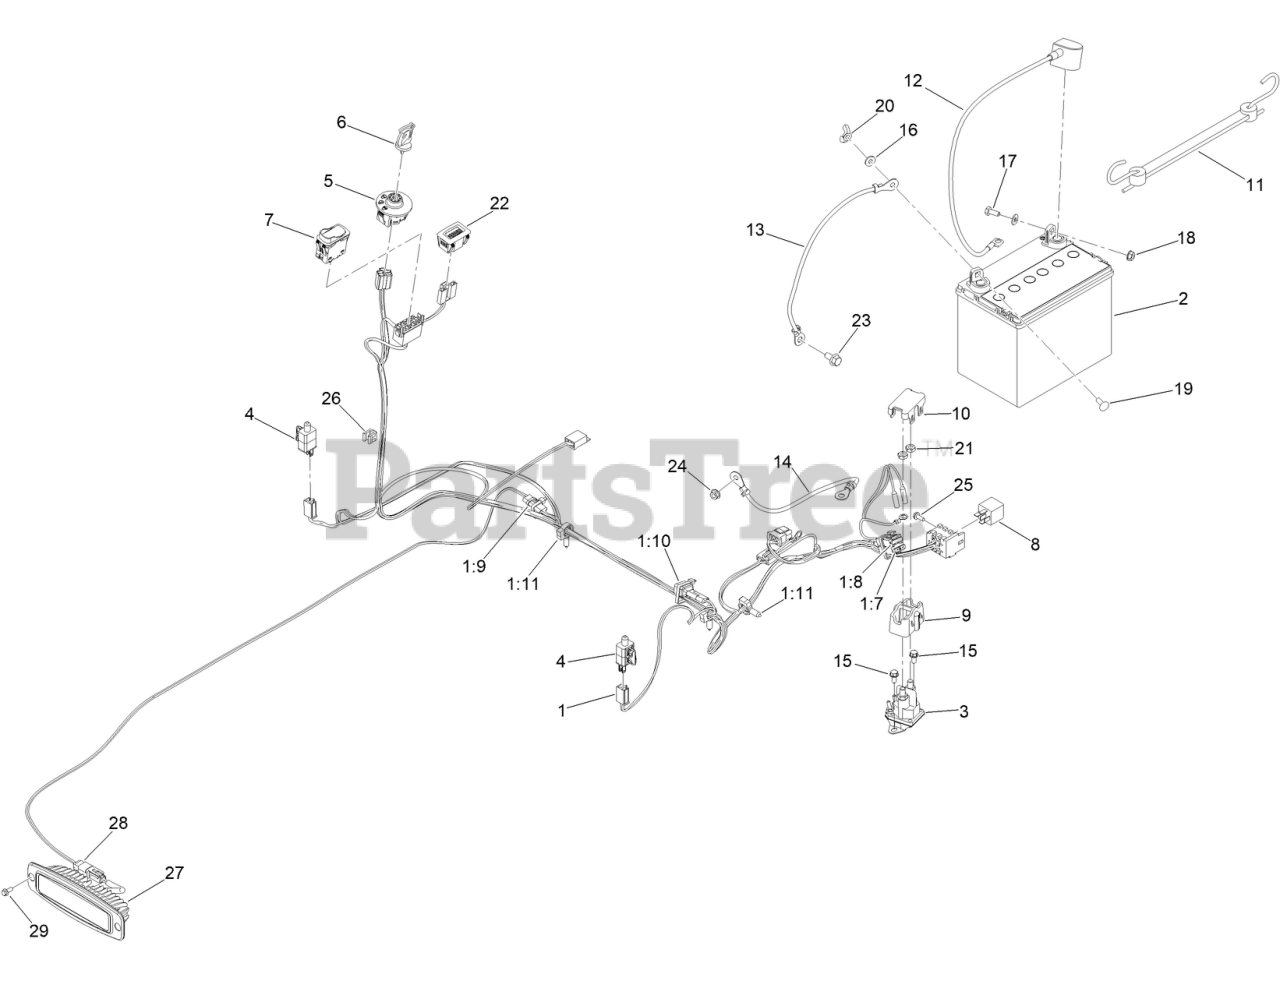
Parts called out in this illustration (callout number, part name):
1	HARNESS-WIRE, MAIN
1:7	FUSE-BLADE, 15 AMP
1:8	FUSE-BLADE, 25 AMP
1:9	CAP-OVER MOLD, 1M/1F
1:11	CLIP-TUBING, HARNESS
2	BATTERY- WET, 12V, 300 CCA
3	SOLENOID
4	SWITCH
5	SWITCH-IGNITION
6	KEY-IGNITION
7	SWITCH-ROCKER, ON-NONE-ON
9	COVER-SOLENOID
10	CAP-SOLENOID
11	HOLDDOWN-BATTERY
12	CABLE-BATTERY,RED
13	CABLE-BATTERY, BLACK
14	CABLE-BATTERY, POSITIVE
15	SCREW-HWH
16	WASHER
17	SCREW-HH
18	NUT-HF
19	BOLT-CARR
20	NUT-WING
21	NUT-HJ
22	HOUR METER
23	SCREW-HHF
24	NUT-HF
25	SCREW-TAPTITE
26	CLIP-EDGE W/TIE, PERPENDICULAR
27	MOUNT-FLUSH, LIGHT
28	HARNESS-WIRE. LED LIGHTS
29	SCREW-HWH
